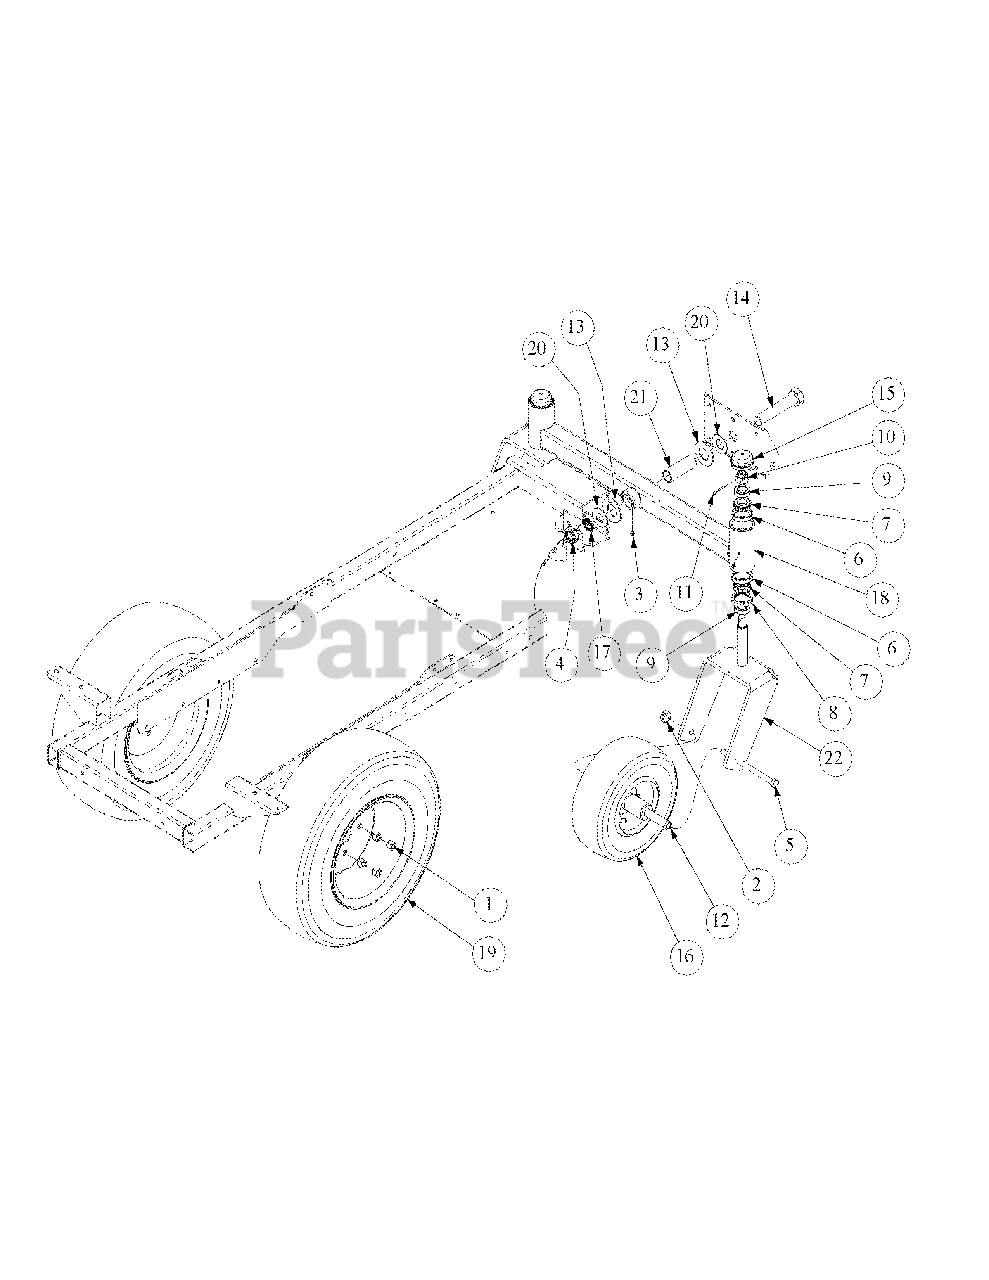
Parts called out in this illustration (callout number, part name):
1	Lug Nut, 1/2-20
2	Nut, 1/2-20, Center Lock
3	Grease Fitting
4	Nut, Jam, 1.0-14, Insert Lock
5	HHCS, 1/2-20, 7.00
6	Cup Bearing
7	Bearing Cone
8	Seal
9	Ring Seal
10	Slotted Nut, 3/4-16
11	Cotter Pin, 5/32, 1.25
12	Wheel Spacer
13	Bell Washer, 1.25 ID
14	Hex Cap Screw, 1-14 x 5.0
15	Grease Cap, 1.986 OD
16	Wheel Assembly, 11 x 4-5.00
17	Retainer Extension, Self Locking
18	Straight Front Axle
19	Wheel, 21 x 7-10
20	Flat Washer, 1.00 ID
21	Spacer, 1.005 ID x 1.25 OD x 3.6
22	Yoke, Caster Wheel
